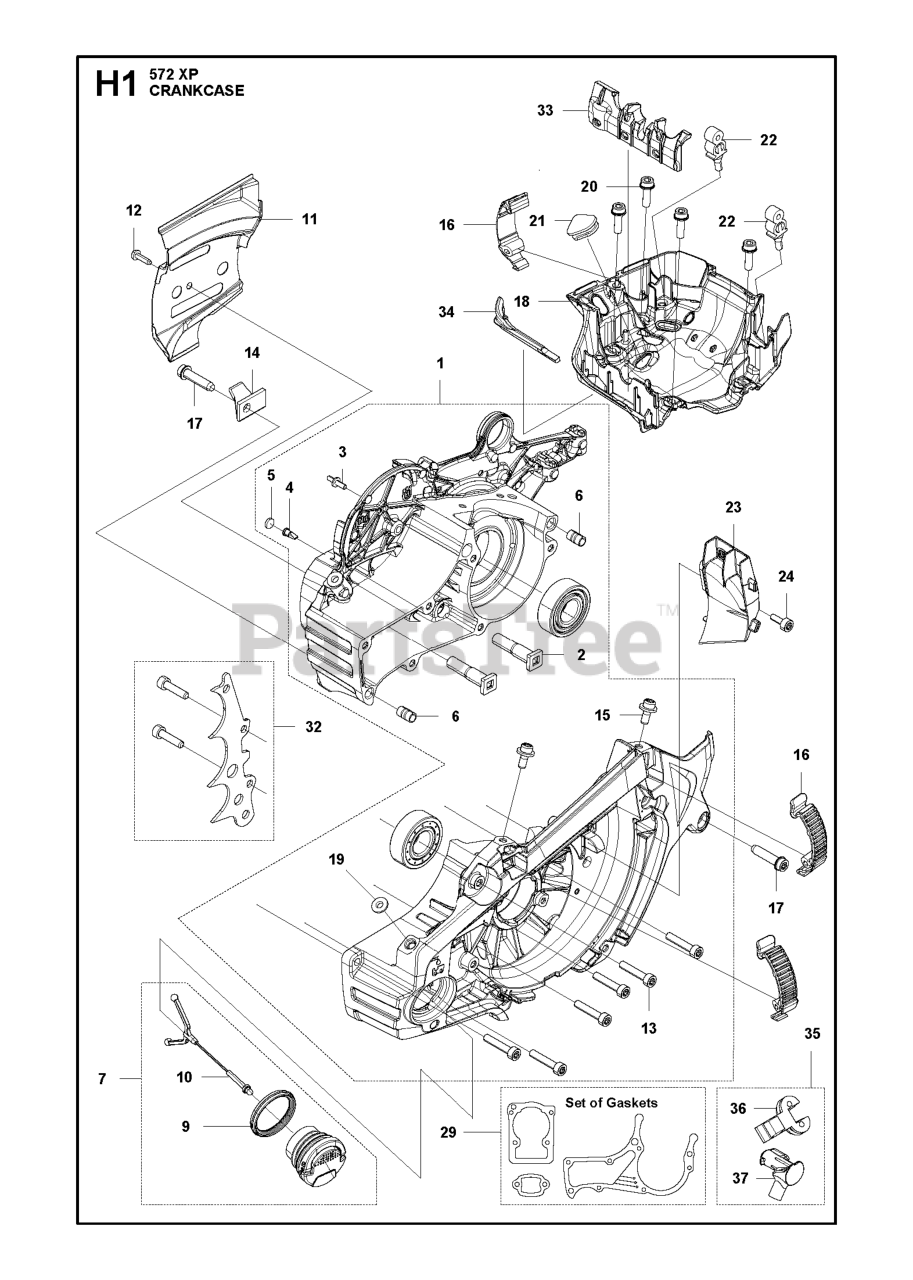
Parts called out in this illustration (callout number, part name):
1	CRANKCASE ASSY H572
4	VALVE-CHECK (DUCKBILL)
5	PLUG
6	GUIDE BUSHING
7	TANK CAP ASSY
11	CHAIN GUIDE PLATE BAR MOUNT
13	SCREW ITXSCM M5X25 12.9 TBO T
14	CHAIN CATCHER
15	SCREW ITXSCM WASHER M5X12 T27
16	CLIP GRAY
18	CARBURETTOR AREA BASE ASSY
19	FIXING WASHER DISTANCE WASHER
20	SCREW ITXSCFM
22	SUPPORT
23	AIR NOZZLE
24	SCREW ITXSCM
29	GASKET KIT H565/H572
32	SPIKE KIT - INNER STD H565/H57
33	SEALING CARB AREA BASE
34	SEALING CRANKCASE - CARB AREA
35	GROMMET KIT H565/H572
37	GROMMET GENERATOR
